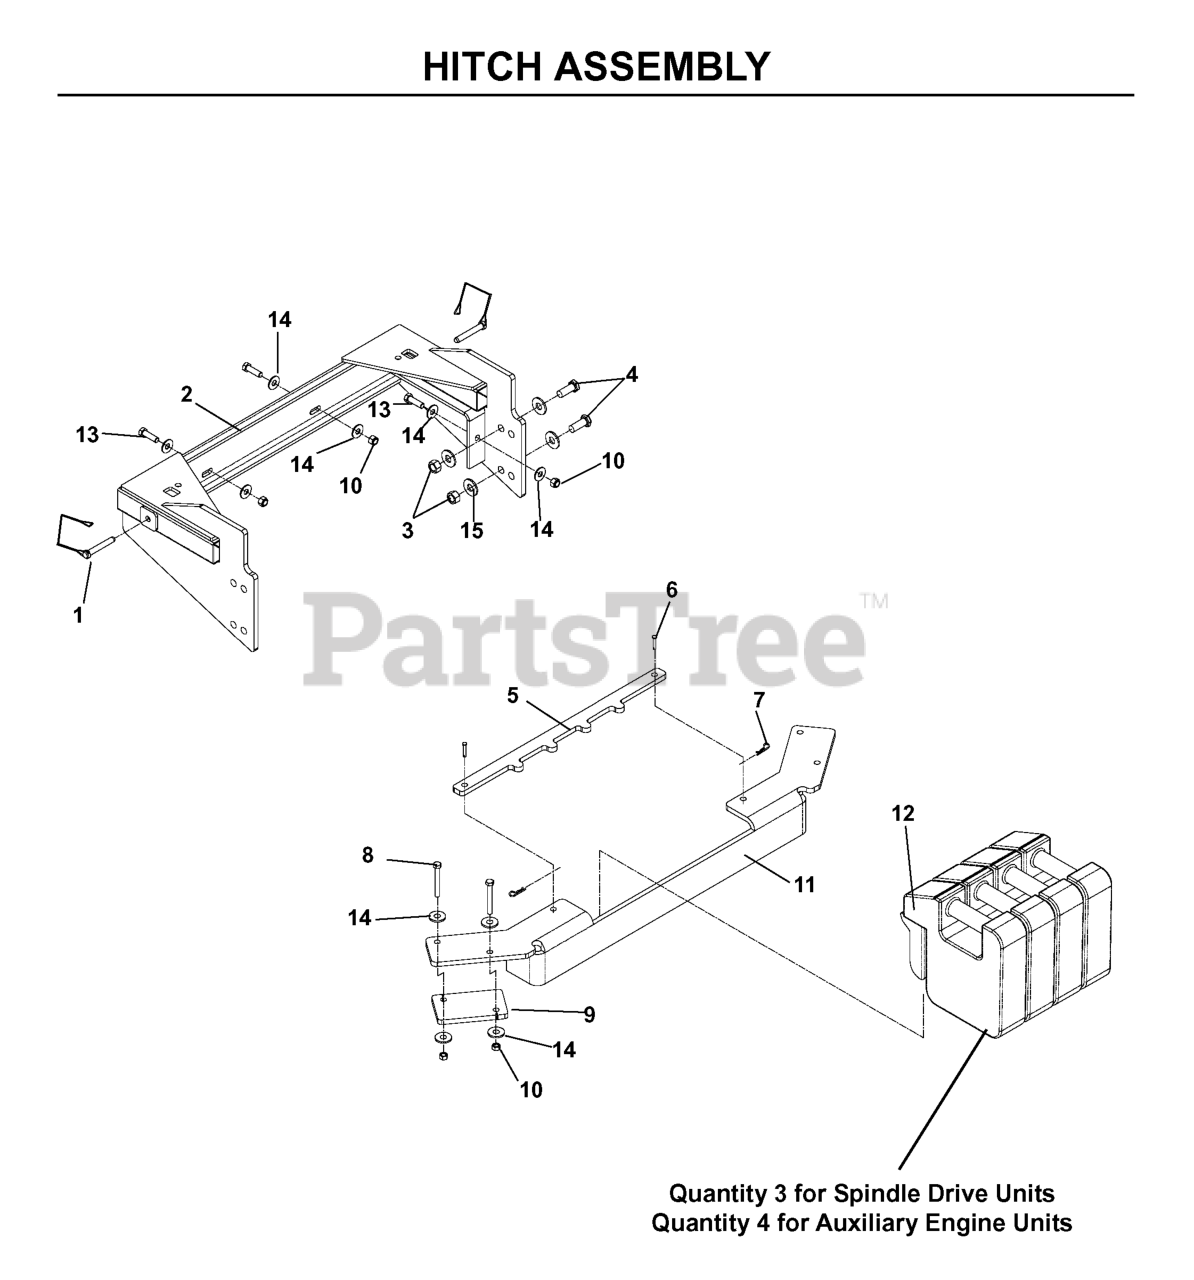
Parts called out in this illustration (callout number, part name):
1	PIN-WIRE LOCK
3	NUT 1/2 NYLOC
5	HOLD DOWN BAR
6	CLEVIS PIN
7	HAIR PIN #11
8	3/8" x 3-1/2" Hex Bolts
9	CLAMP PLATES-FRT WEIGHT BAR
10	NUT 3/8 NYLOC
11	FRONT WEIGHT BAR
12	FRONT WEIGHT PZ DFS
13	BOLT 3/8 X 1.25
14	FLAT WASHER 3/8
15	FLAT WASHER 1/2"
540200828	HIITCH
